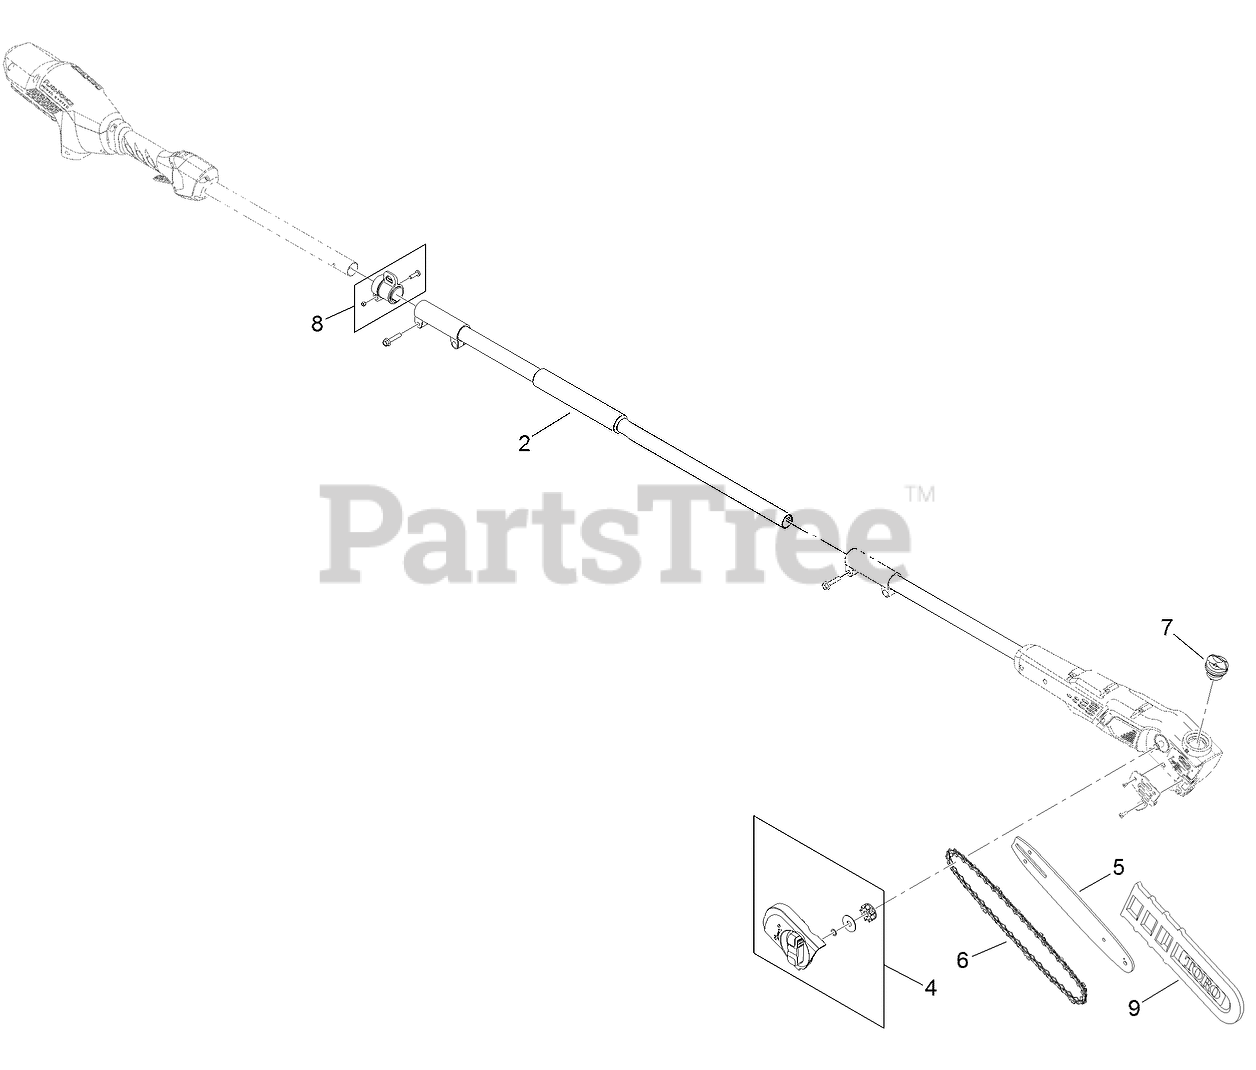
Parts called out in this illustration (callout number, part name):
4	TENSIONER ASM
6	CHAIN
7	CAP-OIL
8	COLLAR-STRAP
9	SLEEVE-BAR
